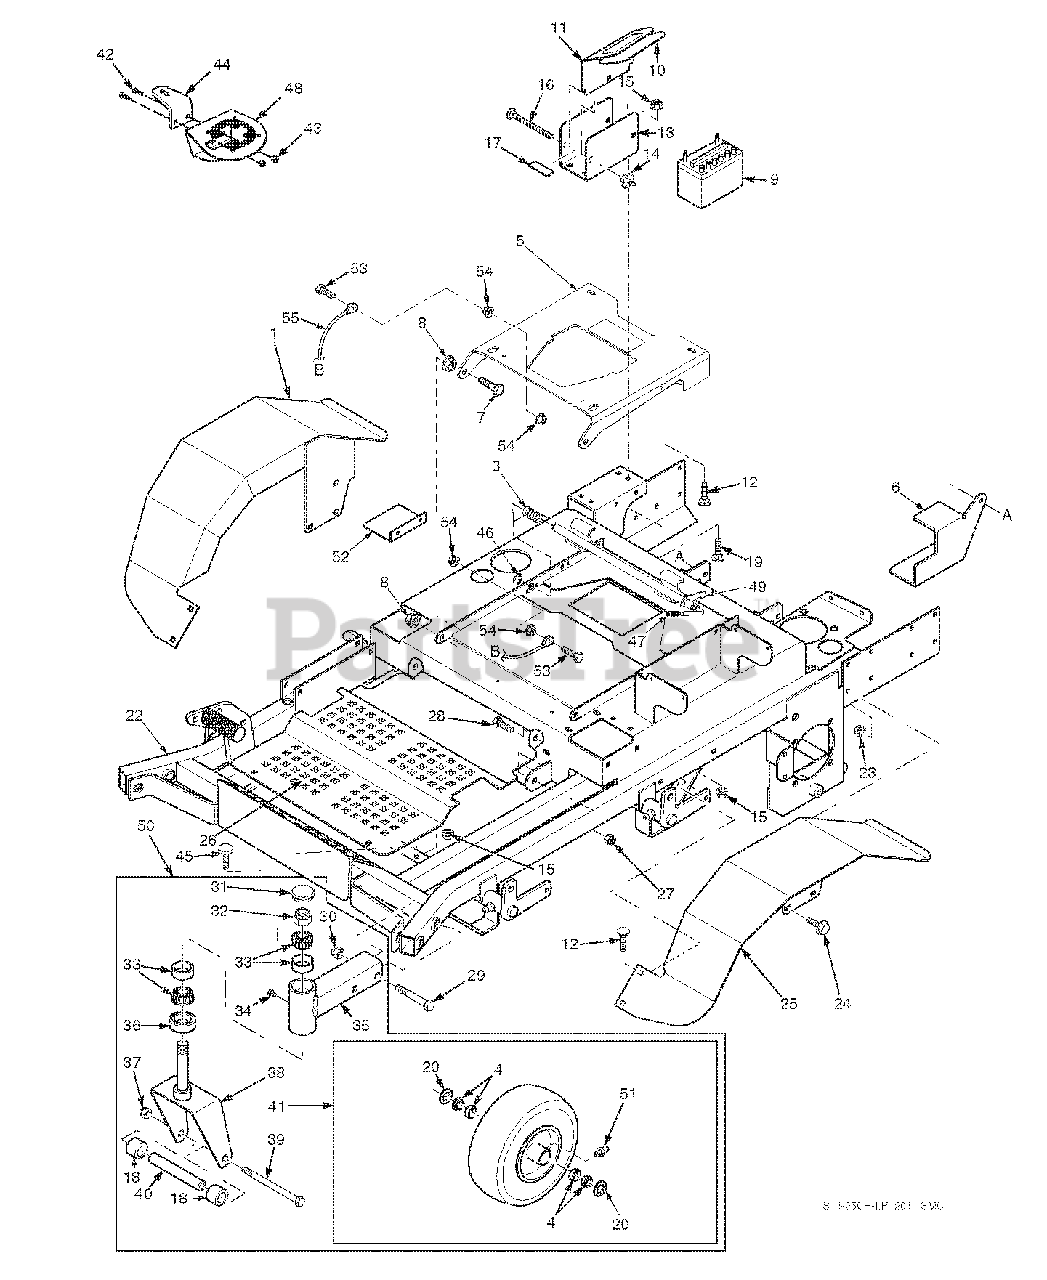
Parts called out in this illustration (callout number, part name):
1	Fender Weldment, RH
2	Bolt, Hex Head, 5/16-18 x 1, Zinc
3	Spring, Seat Latch
4	Bearing w/ Race
5	Seat Plate w/Decal
6	Guard, Fuel Line
7	Bolt, Hex Head 7/16-14 x 1-3/4"
8	Nut, 7/16-14 Serrated Flange
9	Battery
10	Pad, Battery Cover
11	Cover, Battery
12	Bolt, Carriage 5/16-18 x 3/4"
13	Plate, Battery Box
14	Wing Nut, 1/4-20 x 3/4"
15	Nut, Hex Serrated Flange 5/16-18
16	Bolt, Carriage 1/4-20 x 6"
17	Rubber Pad
18	Spacer, Caster Wheel
19	Bolt, Carriage 5/16-18 x 1"
21	Locknut, 3/8-16, Elast. Stop
22	Main Frame w/Decals
23	Nut, Hex Serrated Flange 3/8-16
24	Screw, Hex Serrated Flange 3/8-16 x 1"
25	Fender Weldment, LH
26	Foot Plate
27	Nut, Hex Elastic Stop 3/8-16
28	Bolt, Hex Head 3/8-16 x 1"
29	Bolt, Hex Head 5/8-11 x 4"
30	Nut, Hex Elastic Stop 5/8-11
31	Cap, Grease
32	Nut, Hex Elastic Stop 1.0-14
33	Bearing W/Race
34	Plug, 1/4-28 THD Form
35	Extention Weldment
36	Seal, 2.00" OD. x 1.625" Bore
37	Nut, Hex Elastic Stop 1/2-13
38	Yoke Weldment, Caster
39	Bolt, Hex Head 1/2-13 x 7-1/2"
39	Bolt, Hex Head 1/2-13 x 9-1/2"
40	Sleeve, Caster Wheel
41	Wheel Assy, 52V
41	Wheel Assy, 61V, 72A
42	Bolt, Hex Head 1/4-20 x 3/4"
43	Bolt, Hex Head 1/4-20 x 3/4"
44	Mounting Bracket, STT Cup Holder
45	Bumper, Rubber
46	Retaining Ring, .625" Ext. "E"
47	Grip, Seat Latch
48	Cup Holder Assembly
49	Lever Assembly, Seat Release
50	Caster Wheel Assembly
51	Grease Fitting
52	Cover, Fuel Tank Opening
53	Bolt, Hex Head 1/4-20 x 1-1/4"
54	Nut, Serrated Flange 1/4-20
55	Cable, Seat Stop
